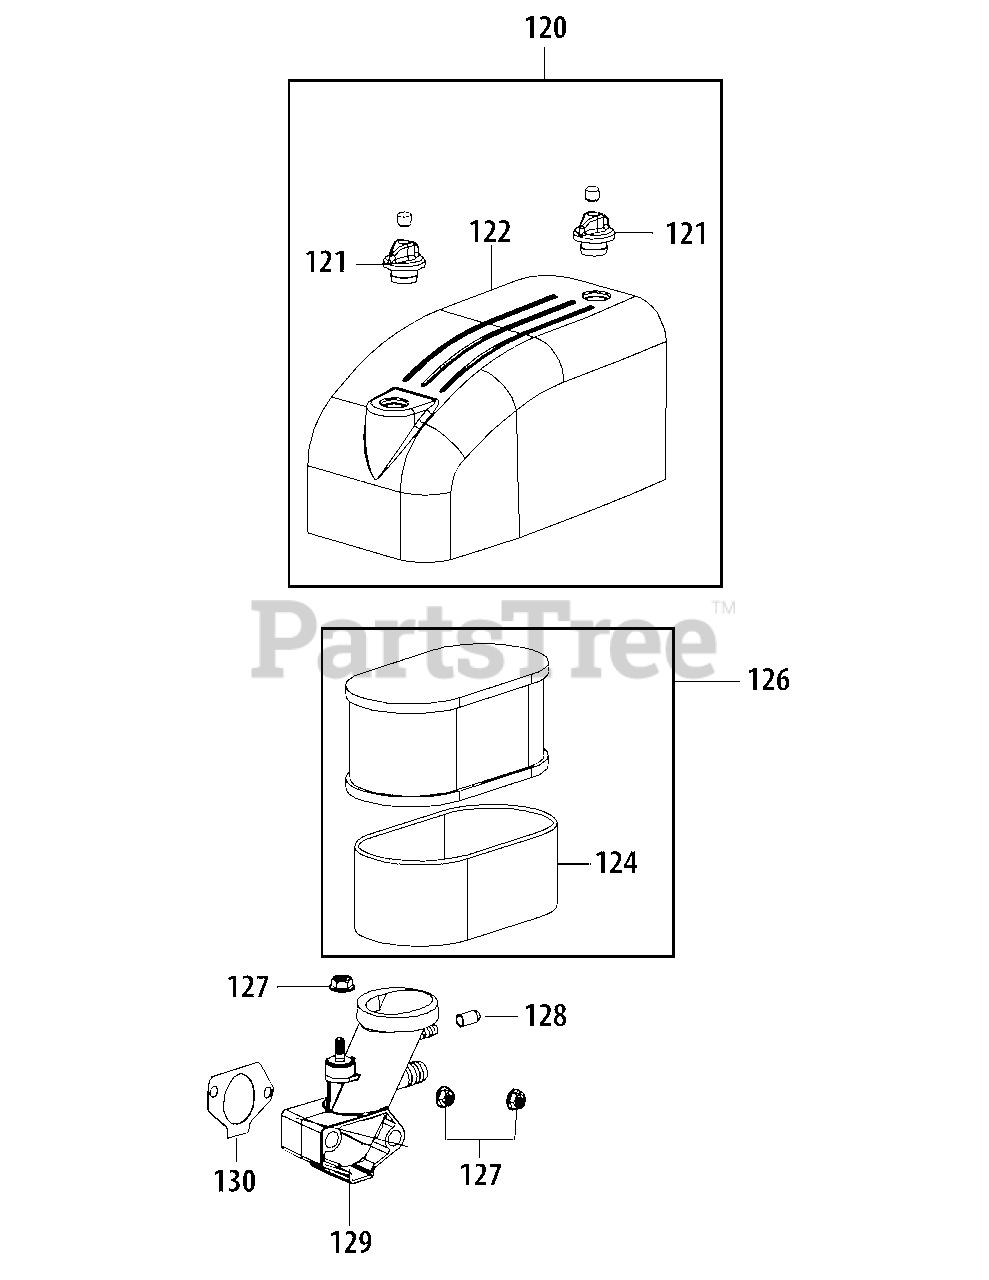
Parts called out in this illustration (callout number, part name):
120	Air Filter Cover Assembly
121	Air Filter Lock Nut
122	Air Filter Cover
124	Sponge Filter
126	Air Filter Assembly
127	Nut M6
128	Rubber Cap
129	Manifold
130	Manifold Gasket
